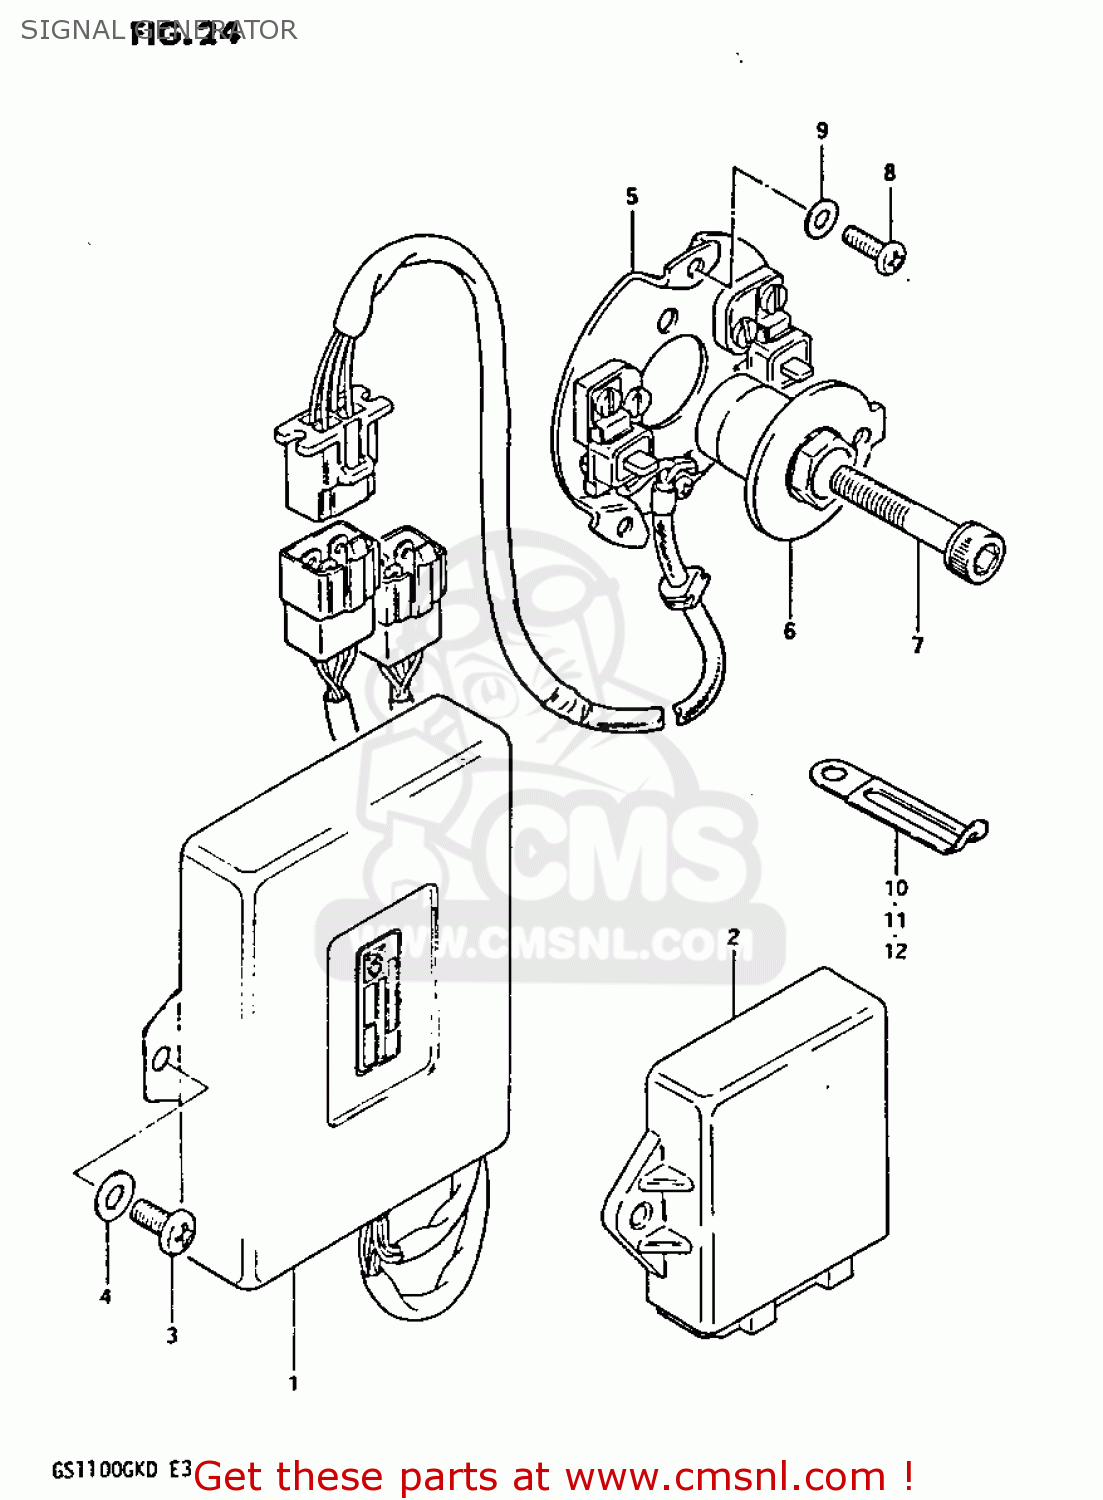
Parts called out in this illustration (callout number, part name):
1	IGNITER UNIT ASSEMBLY
2	IGNITOR UNIT,ESA
3	SCREW 6X12
4	WASHER
5	GENERATOR ASSEMBLY,SIGNAL
6	ROTOR,SIGNAL
7	BOLT 8X45
8	SCREW(5X12)
9	WASHER
10	CLAMP L:35
11	CLAMP
12	CLAMP
